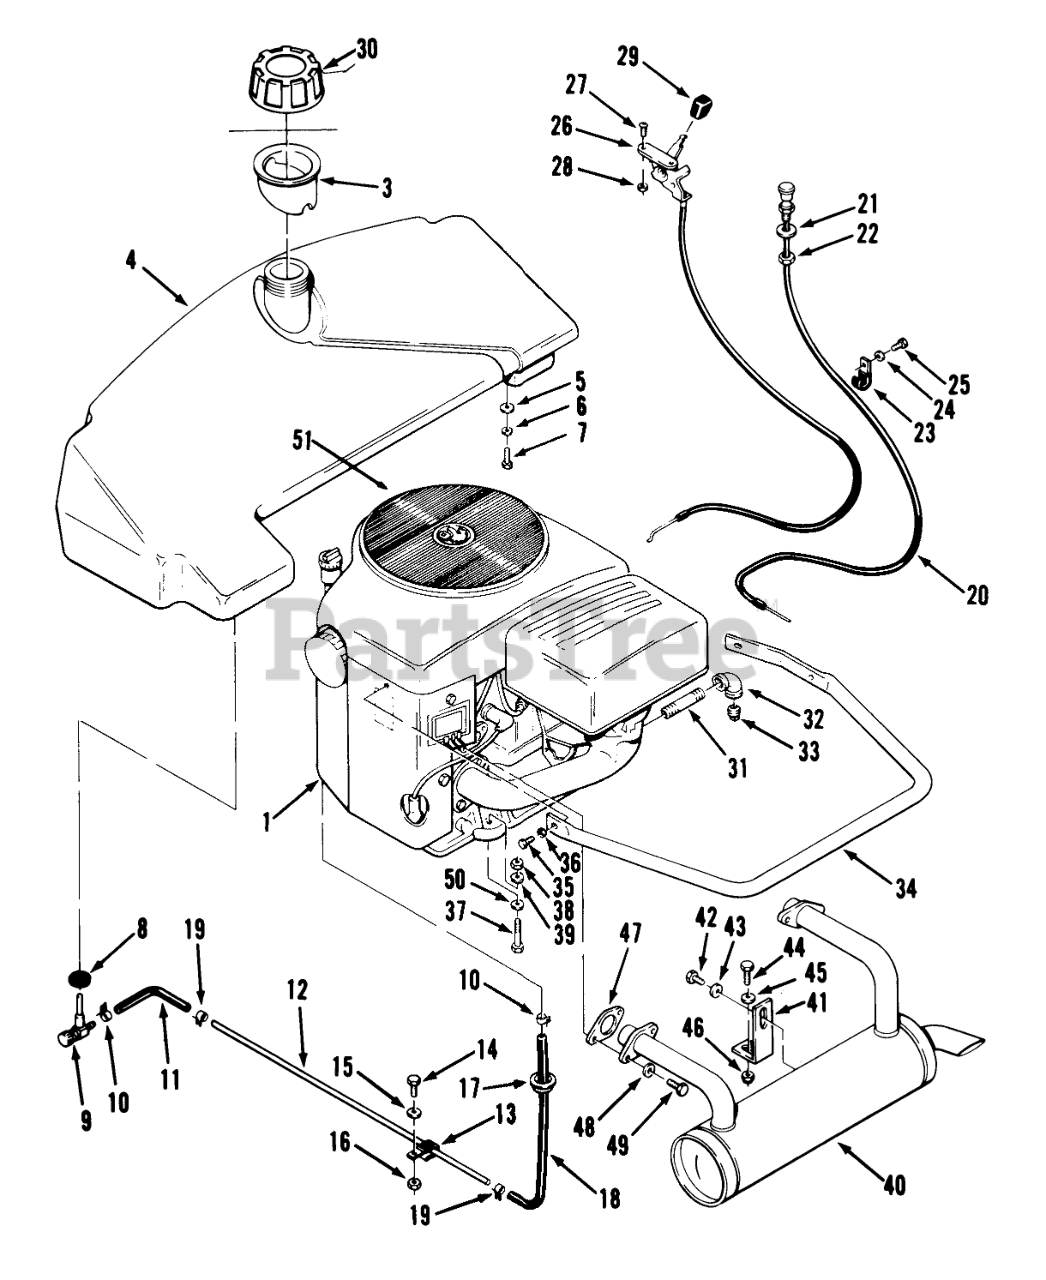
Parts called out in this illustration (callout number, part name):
1	Engine-16 HP-Toro Power Plus-Model P216V-I/11103-A
3	FUNNEL-FUEL TANK
4	TANK-FUEL ASS'Y
5	Collar
6	Lockwasher
7	Bolt
8	BUSHING
9	VALVE-FUEL
10	Clamp
11	Hose5"
12	TUBE FUEL LINE
13	J-CLIP
14	Bolt
15	WASHER 5/16 SAE
16	Nut
17	BUSHING-NYLON 1.093
18	Fuel Hose 18"
19	CLAMP HOSE .5 IN
20	CONTROL-CHOKE
21	Washer
22	NUT-HEX PALNUT
23	CLIP
24	Washer
25	Bolt
26	CONTROL-THROTTLE
27	Screw
28	Nut
29	KNOB-CONTROL
30	GAS CAP ASM
31	NIPPLE-3/8 X 2.5
32	ELBOW 3/8 90 DEG
33	Plug
34	GUARD-AIR CLEANER
35	H H C S
36	Washer
37	Bolt
38	Nut
39	WASHER 5/16 SAE
40	EXHAUST-MUFFLER
41	BRACKET-MUFFLER
42	H H C S
43	WASHER 5/16 SAE
44	Bolt
45	WASHER 5/16 SAE
46	Nut
47	Exhaust Gasket
48	Lockwasher
49	SHCS 5/16-18X.750
50	WASHER
51	Guard
